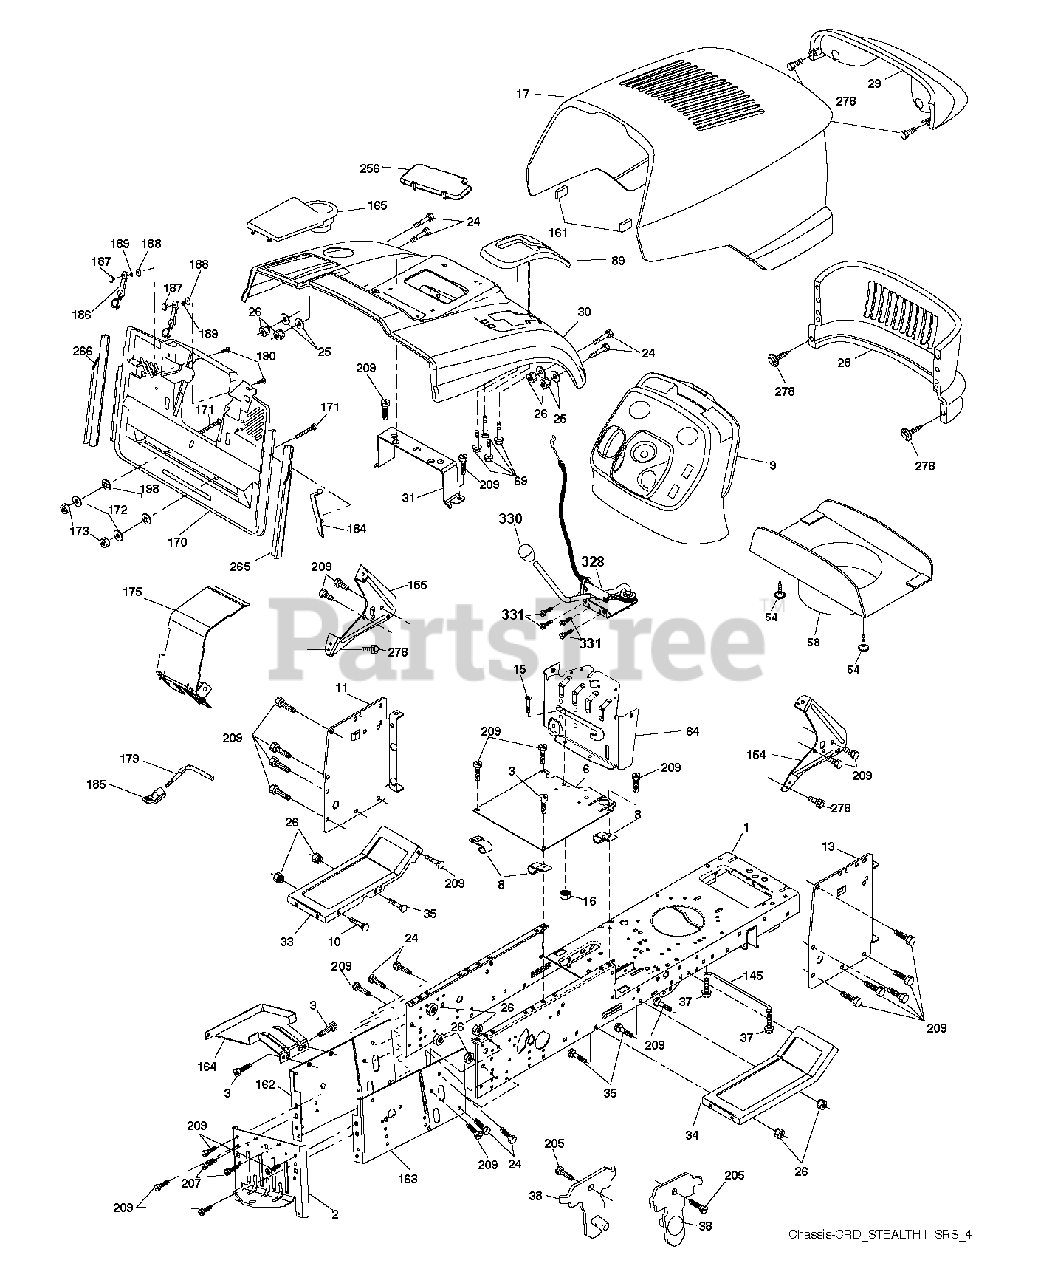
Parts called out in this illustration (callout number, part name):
1	CHASSIS
3	SCREW 3/8-16X3/4
8	CLIP,INSULATOR
10	BOLT D
13	PANEL DASH RH
16	NUT
25	WASHER
26	NUT
31	BRACKET SUPPORT FENDER
54	SCREW.WSHD.HEX10-32X5/8
58	DUCT HOOD
69	SCREW.HI-LO.CONSOLE
145	ROD.PIVOT.HOOD
161	EXTRUSION BUMPER
164	SUPPORT
171	BOLT
172	WASHER
186	LATCH ASSY
187	WELDNUT
189	LOCKWASHER
207	SCREW, 5/16-18 X 1/2
209	SCREW, 3/8-16X3/4
278	SCREW.#10 X 0.750.BOS THREAD
331	SCREW.#10-24X5/8.RN.QU
